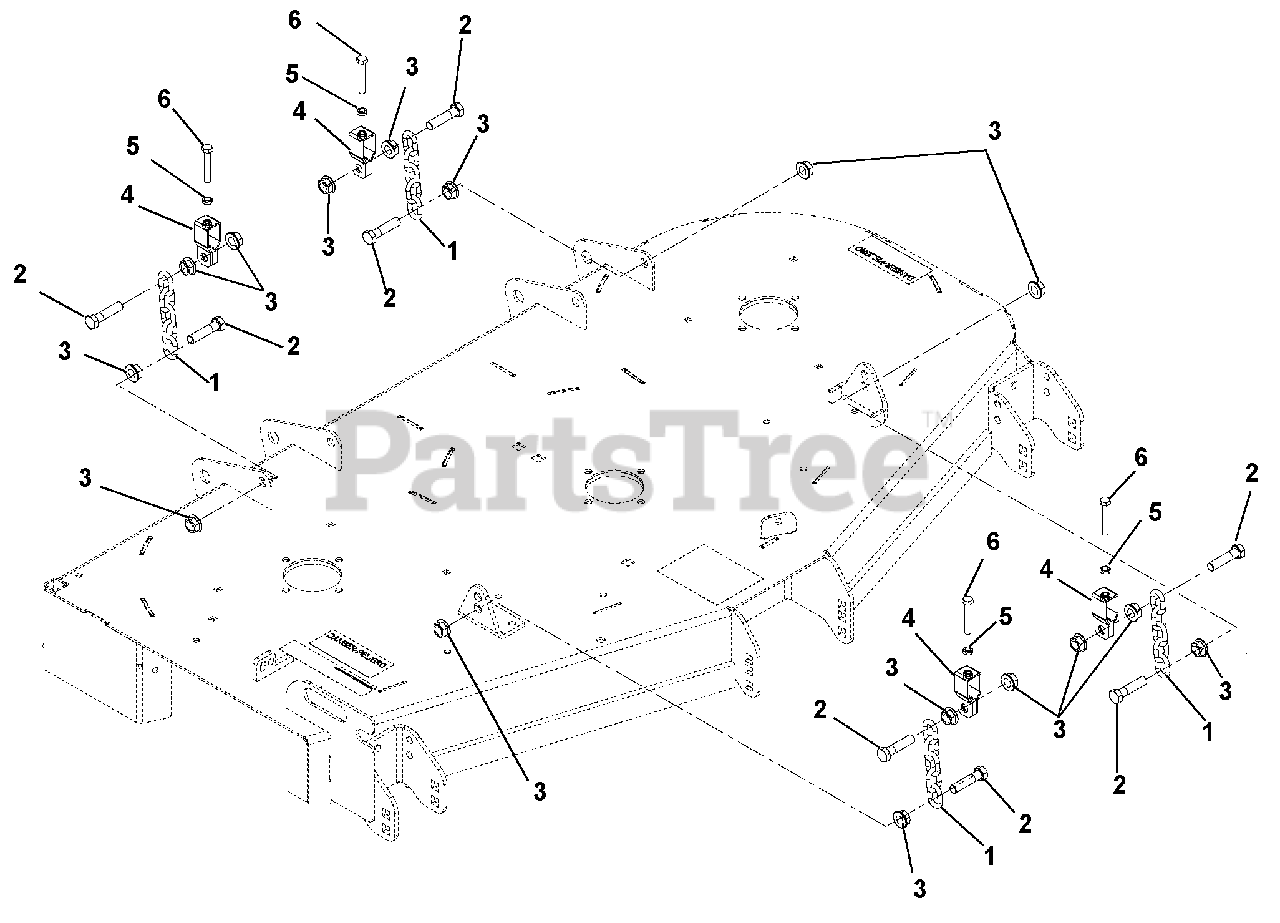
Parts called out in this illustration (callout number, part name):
1	Chain, Link
2	Bolt, Hex M12-1.75 x 50 Class 8.8
3	Nut, Spin Lock, Flange M12-1.75
4	Bracket, Deck Leveling
5	Nut, Jam .312-18
6	Bolt, Hex .312-18 x 2.00 FTH Grade 5
